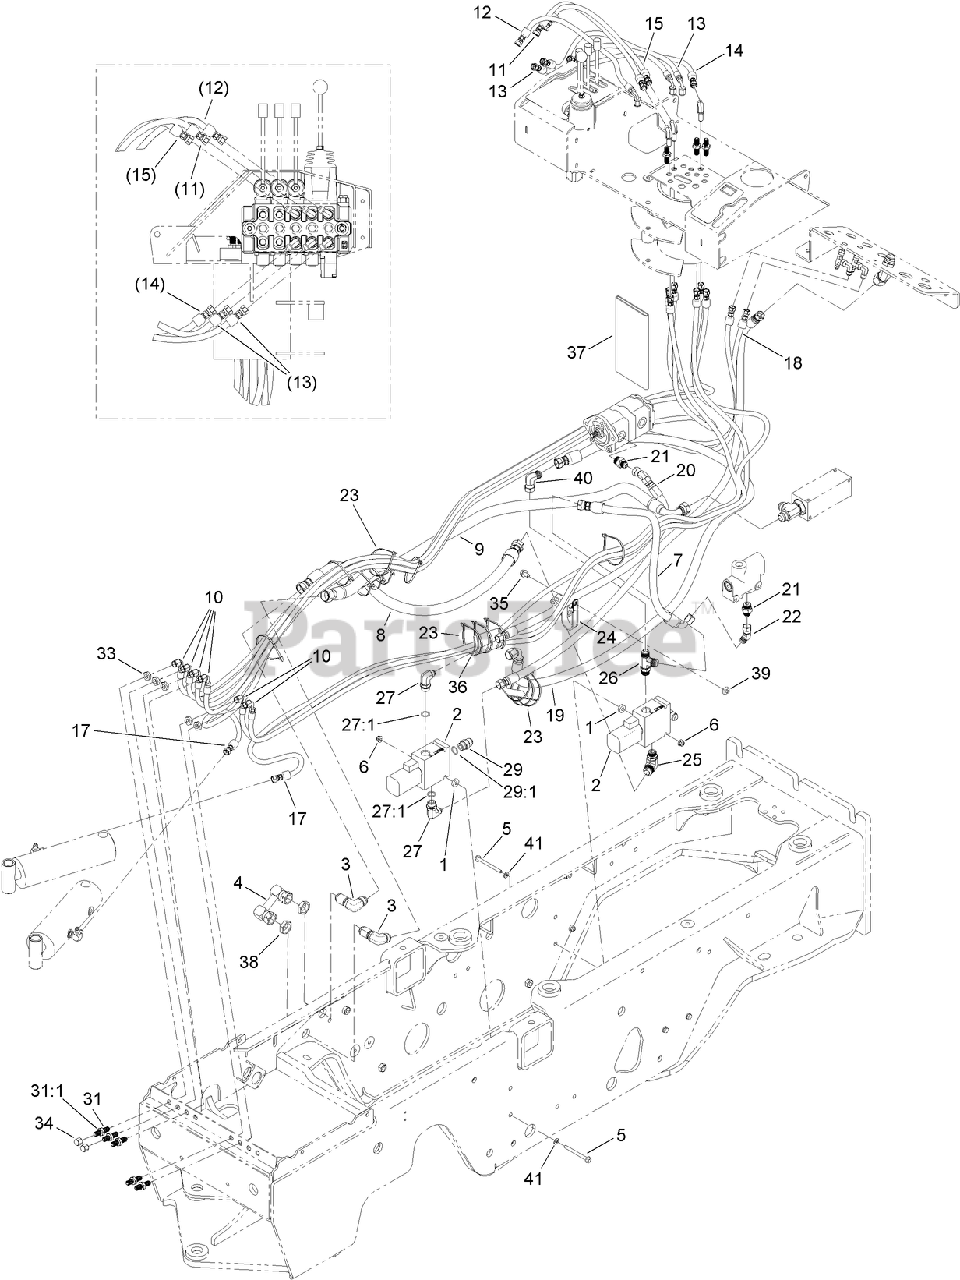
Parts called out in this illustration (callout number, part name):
1	SPACER-PIN, MOUNTING
2	DIRECTIONAL VALVE ASM
3	FITTING-ELBOW, 90
4	FITTING-SPECIAL
5	SCREW-FLANGE
6	NUT-LOCK, HHF
7	HOSE ASM
8	HOSE ASM
9	HOSE ASM
10	HOSE ASM
11	HOSE ASM
12	HYD HOSE ASM
13	HOSE ASM
14	HOSE ASM
15	HYD HOSE ASM
17	HOSE ASM
18	HOSE ASM
19	HOSE ASM
20	HOSE ASM
21	FITTING-STRAIGHT
22	FITTING-SWIVEL, 45
23	TIE-CABLE
24	CLAMP-R, DOUBLE
25	FITTING-ELBOW, 90 DEG
26	FITTING-TEE
27	FITTING-90 DEG
27:1	O-RING
29	FITTING-STRAIGHT
29:1	O-RING
31	UNION-BULKHEAD
31:1	NUT-LOCK, BULKHEAD
33	NUT-LOCK, BULKHEAD
35	SCREW-HHF
36	PROTECTOR-HOSE
37	SLEEVE-PROTECTIVE
38	NUT-LOCK, BULKHEAD
39	NUT-SQUARE
40	ADAPTOR
41	WASHER-PLAIN
